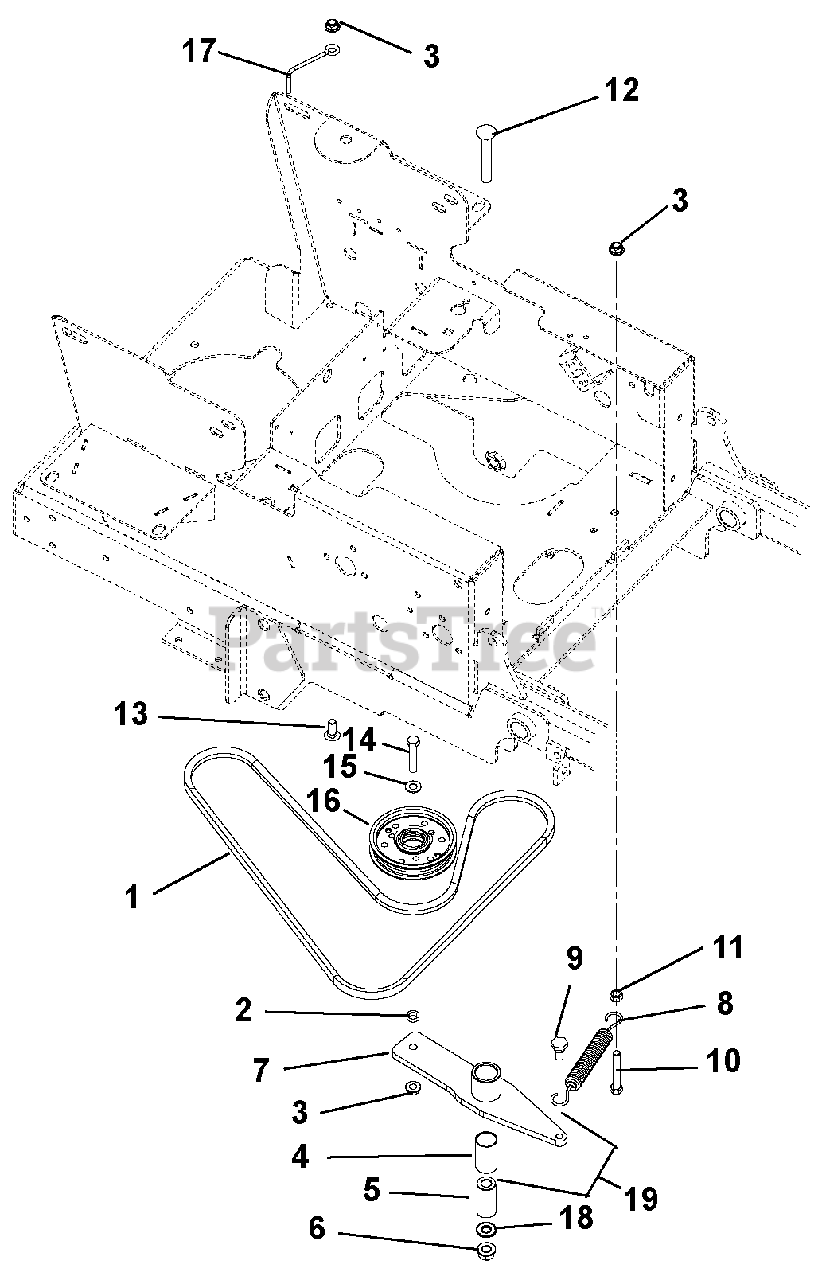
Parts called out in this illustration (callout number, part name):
1	V-BELT, 4L-WRAPPED
2	BSHG-SLV .377X.624X.235
3	@NUT-LK-NYL-FLG .38-16 YWZC
4	BSHG, 1.00 X 1.125 X 1.937
5	BSHG, SPCR .502X.997X2.03 PM
6	@NUT-LK-NYL-FLG .50-13 YWZC
7	WMT-HYDRO DRIVE IDLER ARM
8	SPRING, EXTENSION
9	BLT,SHLDR EP .38-16X.30 HEX YZ
10	@BLT-HEX .38-16X2.50 GR5 YWZC
11	@NUT-HEX .38-16 YWZC
12	@BLT-HEX .50-13X3.25 GR5 YWZC
13	@BLT-RDHDSQNK .38-16X1.00 G5YZ
14	@BLT-HEX .38-16X2.00 GR5 YWZC
15	@WSHR-FL-STL.406X.812X.065 YWZ
16	IDLER-FLAT 4.00 X .38 NWHAMSHR
17	BELT FINGER
18	WSHR-FL-STL.511X1.441X.125 YWZ
19	ASM, IDLER PIVOT ARM (HYDRO)
